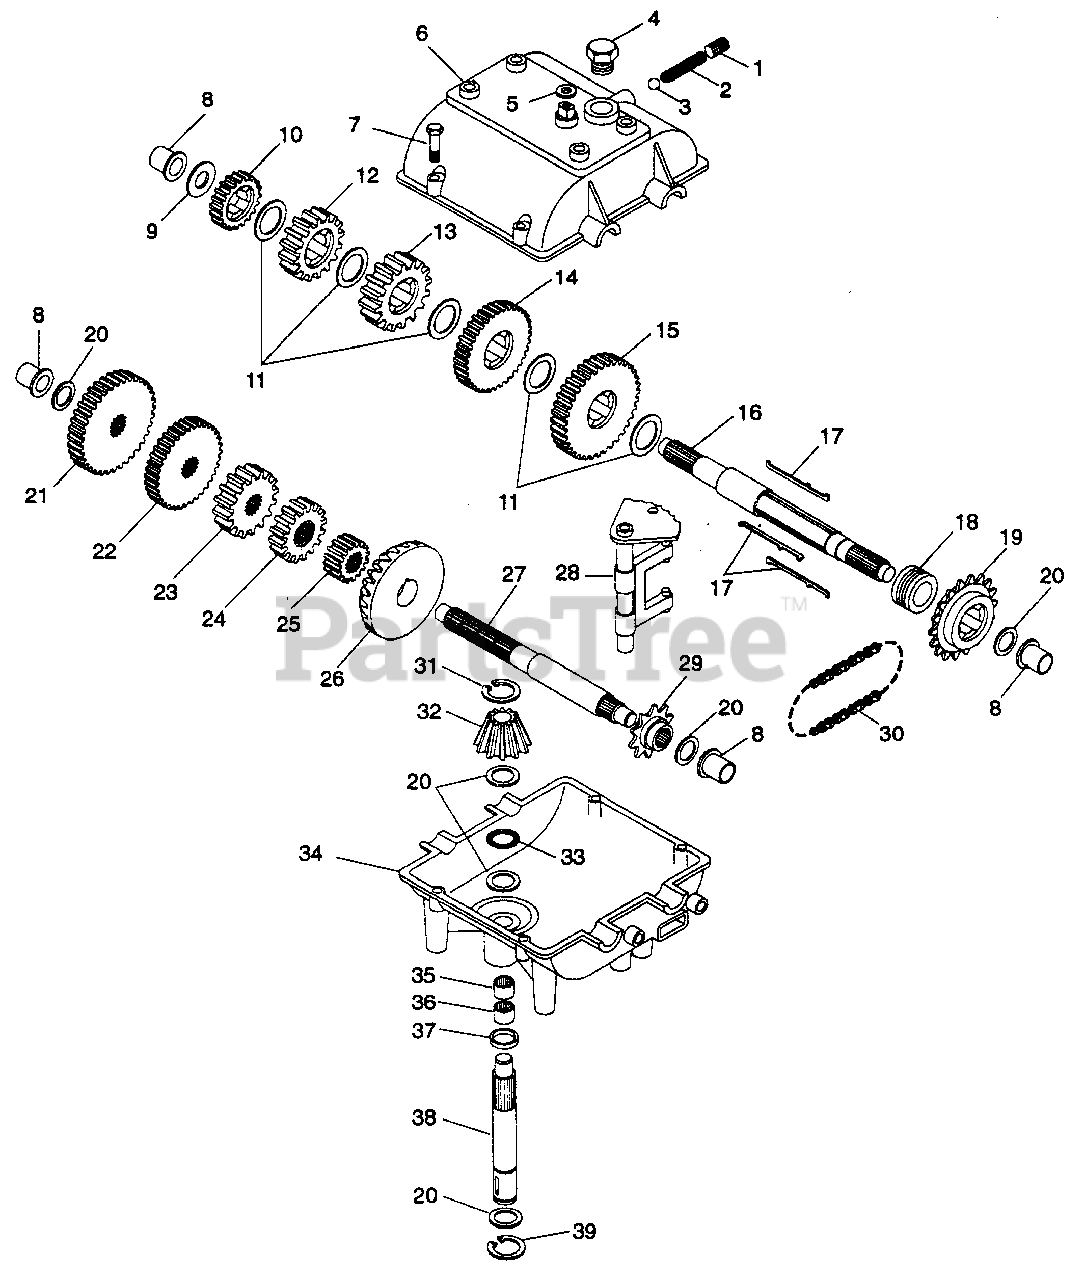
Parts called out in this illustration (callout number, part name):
1	SCREW, SET 3/8-16 X 3/8
3	BALL, STEEL 5/16
4	PLUG, THREADED
5	SEAL, SQUARE CUT
6	COVER, TRANSMISSION
7	SCREW, HHD TAPTITE, 1/4-20 X 1.25
8	BUSHING, FLANGED
9	WASHER, THRUST
10	GEAR, SPUR(27 TEETH)
11	WASHER, THRUST
12	GEAR, SPUR(30 TEETH)
13	GEAR, SPUR(32 TEETH)
14	GEAR, SPUR(35 TEETH)
15	GEAR, SPUR(37 TEETH)
16	SHAFT, OUTPUT & BRAKE
18	COLLAR, SHIFT
19	SPROCKET(18 TEETH)
20	WASHER, THRUST
21	GEAR, SPUR(23 TEETH)
22	GEAR, SPUR(20 TEETH)
23	GEAR, SPUR(18 TEETH)
24	GEAR, SPUR(15 TEETH)
25	GEAR, SPUR(12 TEETH)
26	GEAR, BEVEL(42 TEETH)
27	SHAFT, COUNTER
28	ROD & FORK ASSEMBLY, SHIFT
29	SPROCKET(9 TEETH)
30	CHAIN, ROLLER(NO. 41 CHAIN, 24 LINKS)
31	RING, RETAINING
32	BEVEL PINION, INPUT
33	BEARING, THRUST
34	CASE, TRANSMISSION
35	BEARING, NEEDLE
36	BEARING, NEEDLE
38	SHAFT, INPUT
39	RING, RETAINING
